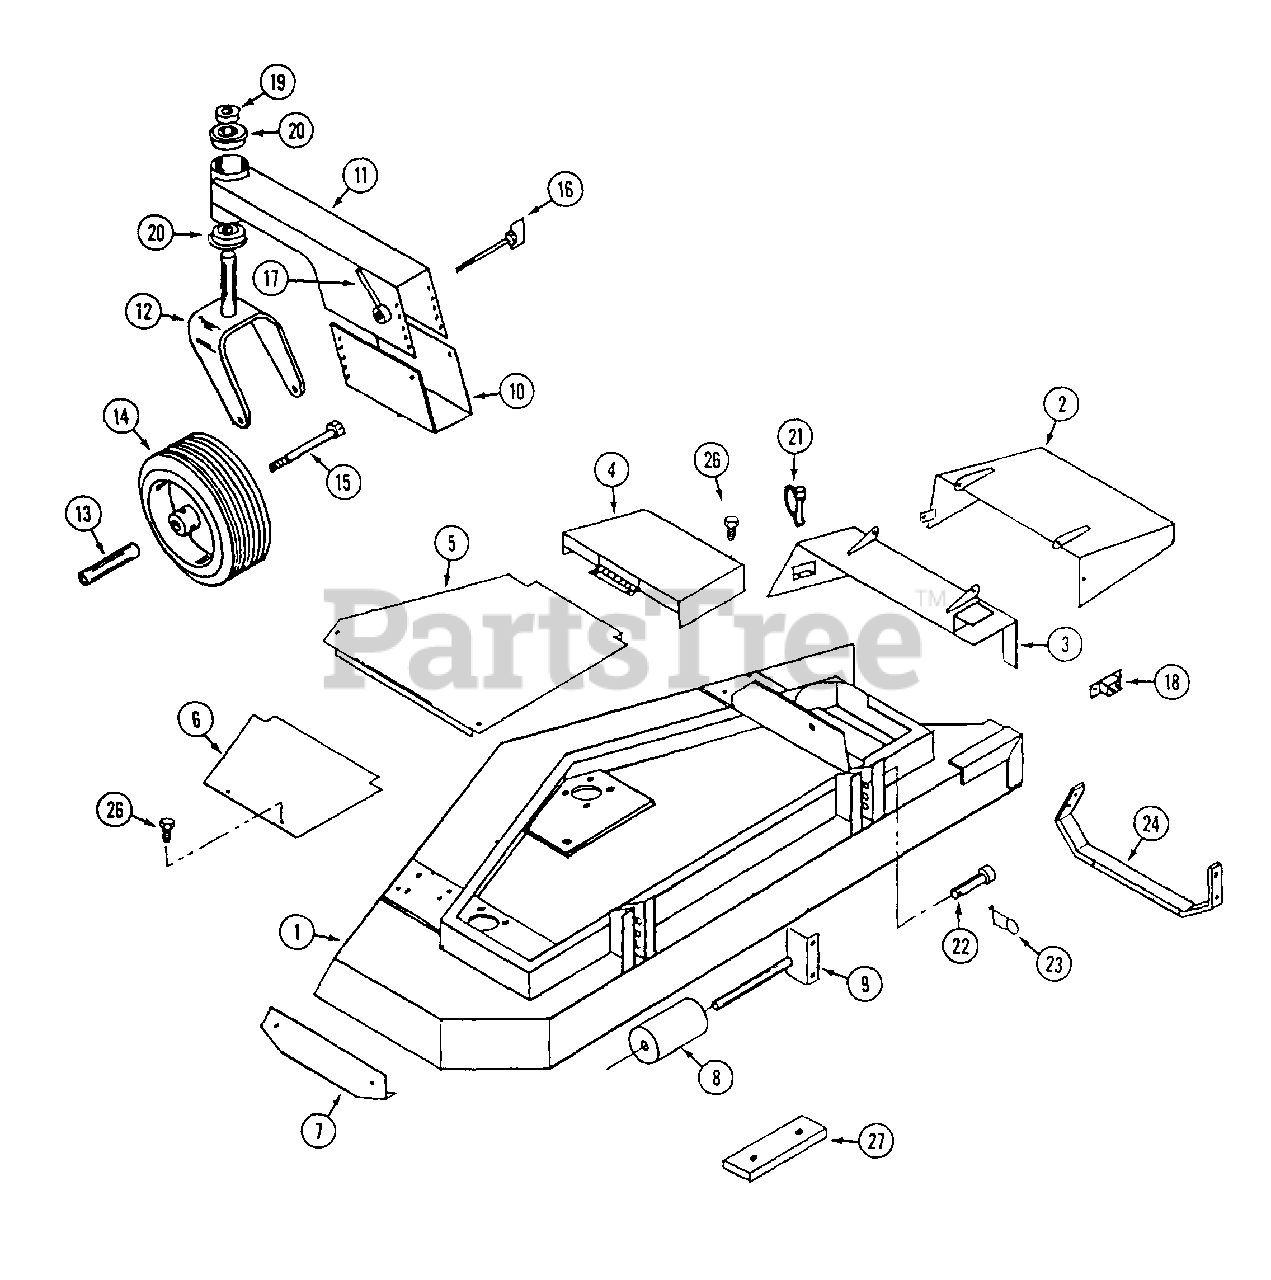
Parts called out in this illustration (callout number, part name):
1	DECK - 62"
2	CHUTE - foot guard
3	MOUNT - foot guard
4	COVER - pulley
5	COVER - center
7	SHOE - skid L.H.
8	ROLLER - anti-skid
9	SHAFT - roller
10	BRACKET - gauge wheel mount
11	MOUNT - gauge wheel
12	FORK - gauge wheel
13	AXLE - gauge wheel
15	BOLT - 1/2" - 13 x 6-1/2"
17	NUT - gauge wheel handle
18	BREAKER - circuit - 10 amp
19	COLLAR - set 1"
21	PIN - "fas-tatch"
23	PIN - cotter, hair
24	SHOE - skid R.H.
26	BOLT - 1/4" - 20 x 3/4"
27	WEIGHT - tail, 13 lb.
